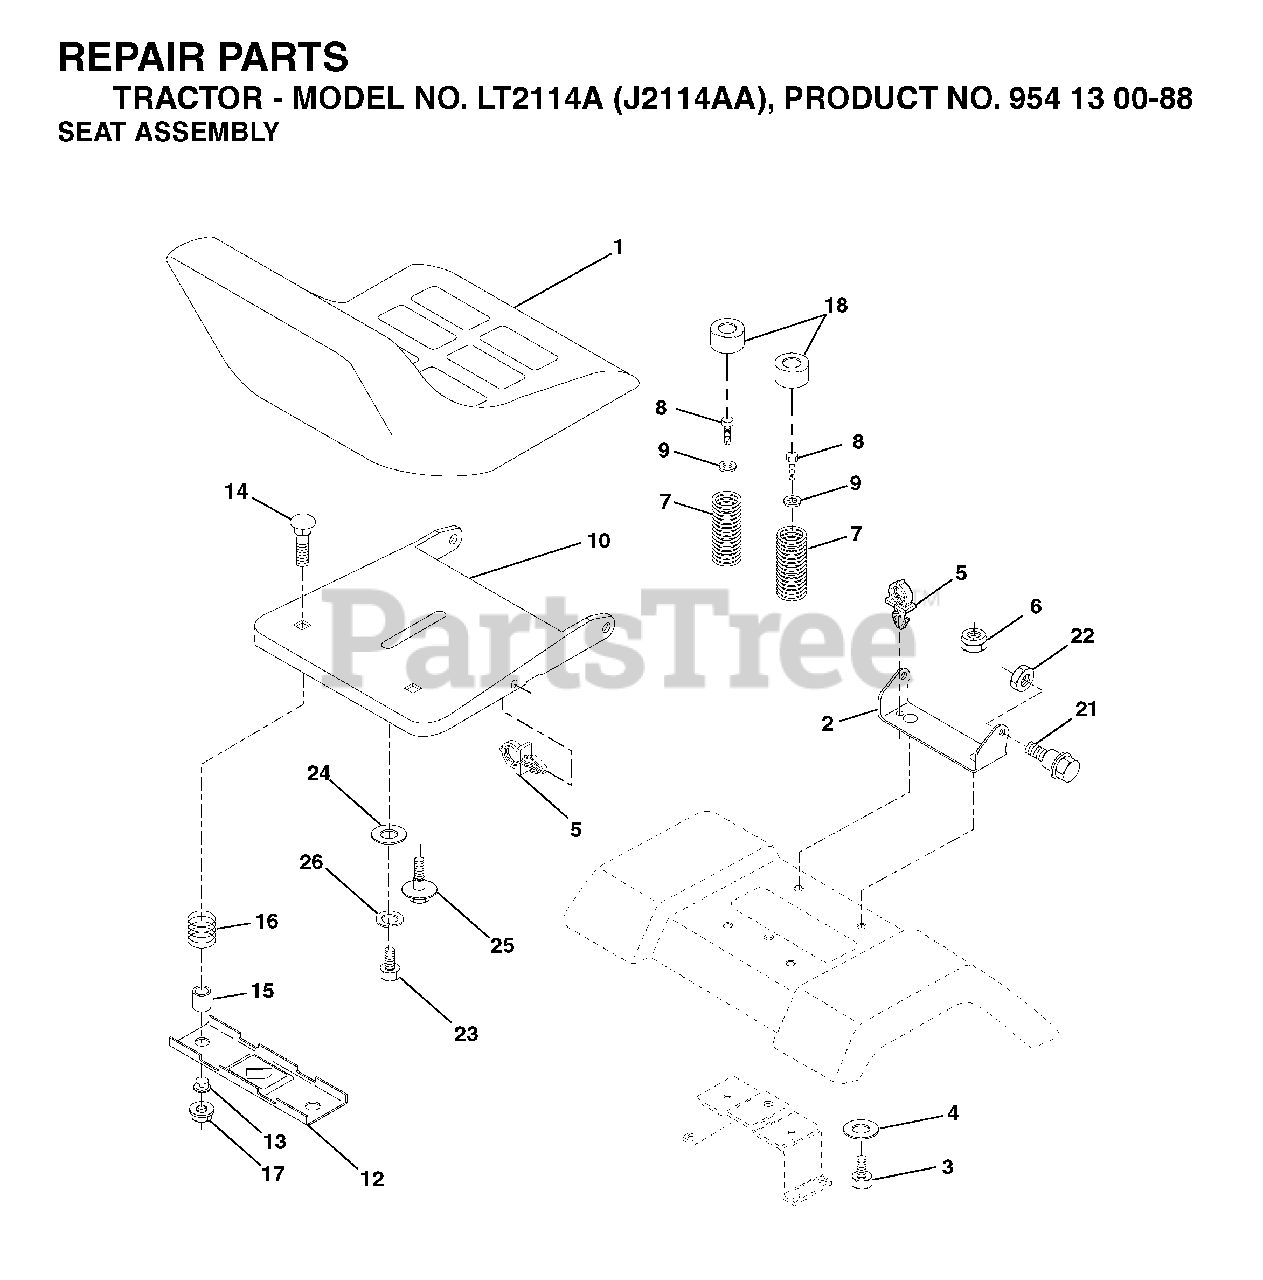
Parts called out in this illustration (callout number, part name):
2	SEAT PIVOT BRKT
4	WASHER PM
5	PUSH CLIP
6	NUT
7	SPRING COMPRESSION
8	SCREW 3/8-16X1
9	WASHER
10	PAN SEAT
12	BRKT SWITCH
14	BOLT.ROUND.HEAD.SQUARE.NECK
15	SPACER SPLIT 28X.96
17	NUT T
18	CAP SPRING
21	BOLT.SHOULDER.5/16-18
22	NUT.71038.31-18.HEX.NYLOCK
23	BOLT.HEX.BLACK
25	BOLT,SHOULD
26	LOCKWASHER
